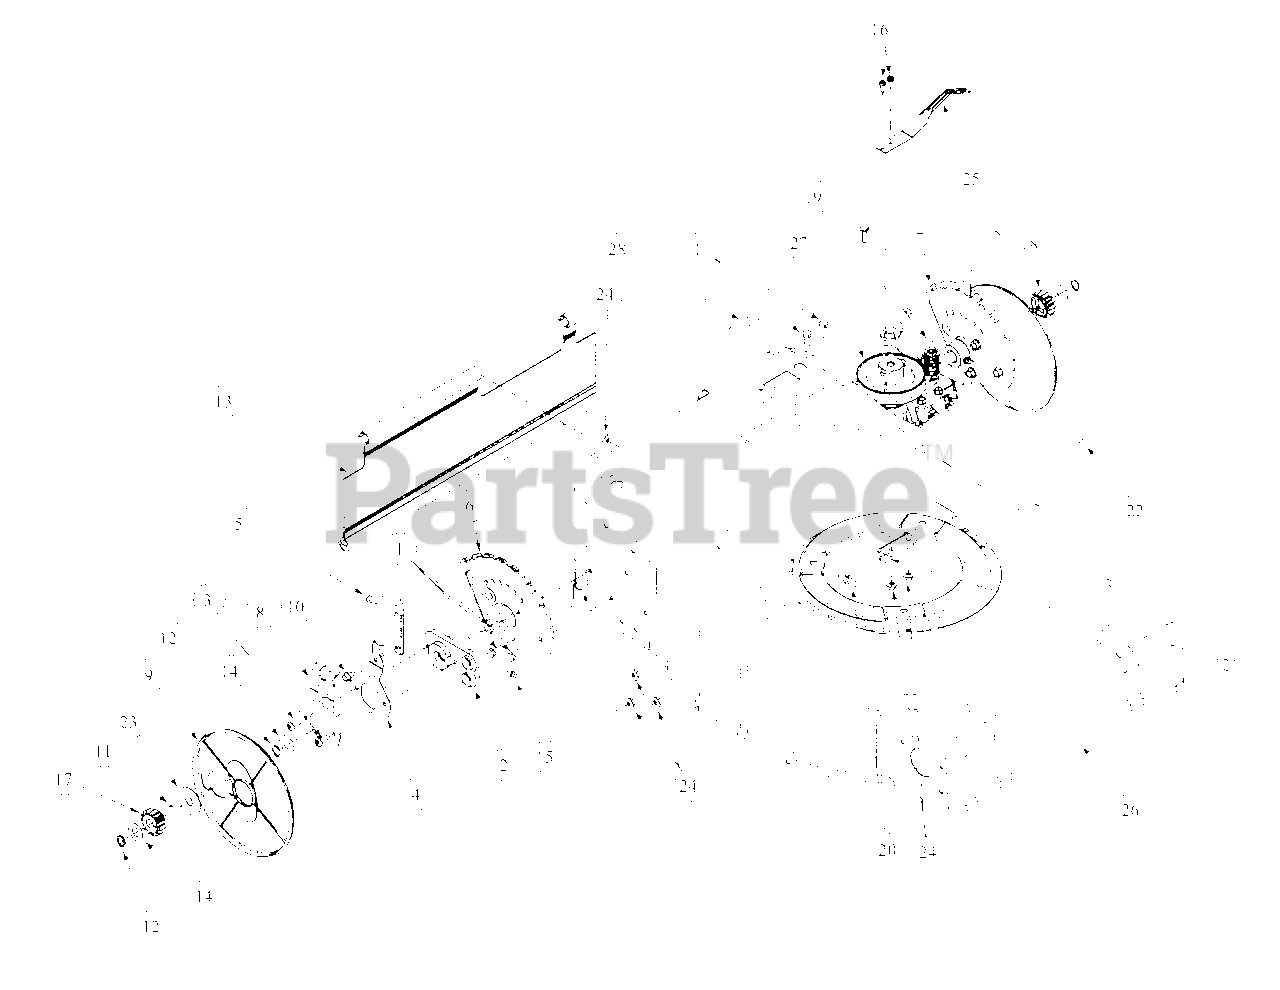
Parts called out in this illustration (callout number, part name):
1	Hex, Cap Screw, 1/4-20, .620
2	Pivot, Wheel, Bracket Assembly, 2 Pos
3	Screw, TT, 1/4-20, .625
4	Height Adjuster, Spring Plate
5	Height Adjuster, Handle
6	Height Adjuster, Bracket, Right Rear
7	Height Adjuster, Bracket, Left Rear
8	Spring Lever, Support, Bracket
9	Drive Wheel, Dust, Cover
10	Screw, 1/4-20, .375, Index Washer
11	Dowel Pin, 3/16 x 3/4
12	Retainer Ring, .500 Dia Heavy Duty
13	Trailshield, 6.12 x 17.91 Long
14	Flat Washer, .508 ID x 1.00 OD x .020
15	Grease Fitting
16	Screw, #10-24-24, 0.500, Hex Index Washer
17	Pinion Gear, 15T, With Ratchet, R
18	Pinion Gear, 15T, With Ratchet, L
19	Extension Spring, .75 OD x 2.37
20	Belt, Pin, Keeper
21	Transmission, Spring Bracket, Tuff Torque
22	Belt, V Type, 3/8 x 32.92 Long
23	Thrust Washer, .510 x 1.562 x .03
24	Nut, 1/4-20, Hex Flange, Lock
25	Shift Spring
27	Transmission Assembly, 3-Speed
28	Label, Shift, 21
